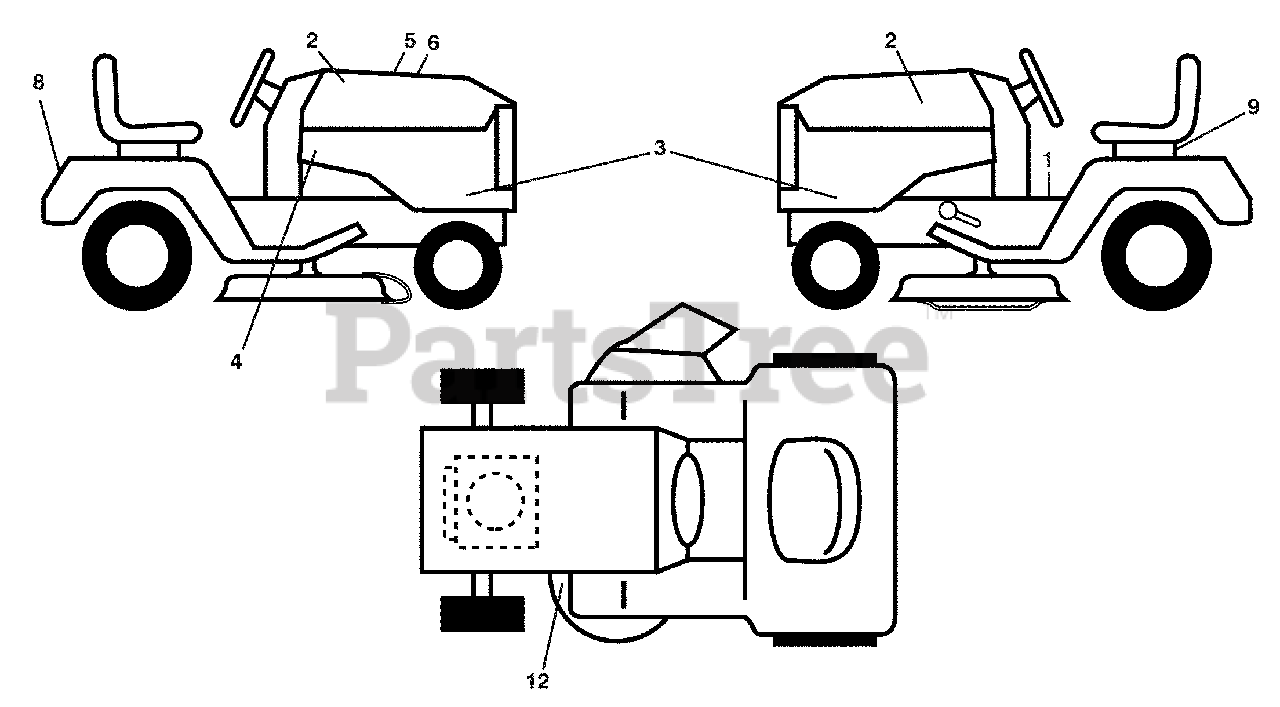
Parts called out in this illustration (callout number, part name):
1	Decal, Fender Warning
2	Decal, Hood
3	Decal, Hood Panel SD
4	Decal, Hood E85 Warning
5	Decal, Customer Respons.
6	Decal, Replacement
8	Decal, Fender
9	Decal, Battery Dnge/Poi
12	Decal, Mower V-Belt Schematic
